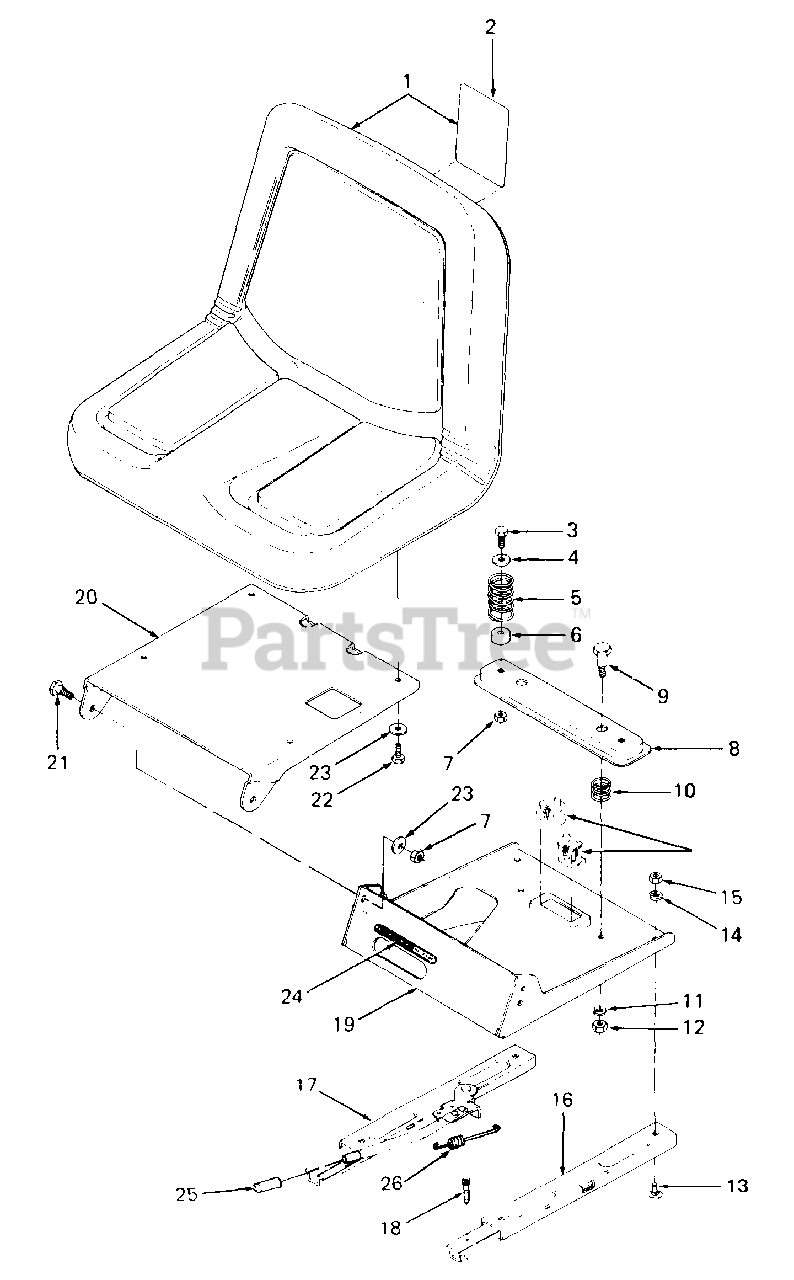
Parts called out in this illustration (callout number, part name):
1	Seat w/Graphic
2	Graphic, Caution
3	Screw, Hex Cap, 5/16-18 X.88 Lg GR5
4	Washer, Flat, .344 x .875 x .06 Thk
5	Spring, Comp, 1.28 OD x 2.18 Lg
6	Bushing, .930 OD X.50 Lg
7	Nut, Hex Center Lock, 5/16-18 GR5
10	Spring, Comp, 1.00 OD X.86 Lg
11	Washer, Lock, 3/8
12	Nut, Hex, 3/8-16 GR5
13	Bolt, Sht Nk Carriage, 5/16-18 X.62 Lg
14	Washer, Lock, 5/16
15	Nut, Hex, 5/16-18 GR5
16	Slide, Seat - LH
17	Adjuster, Manual Seat - RH
18	Screw, Socket Hd Cap, 5/16-18 x 1.00 Lg
22	Screw, Hex Cap, 5/16-18 X.75 Lg GR5
23	Washer, Bell, .345 X.88 X.060 Thk
24	Label, Seat Adjustment
25	Cover, Handle
